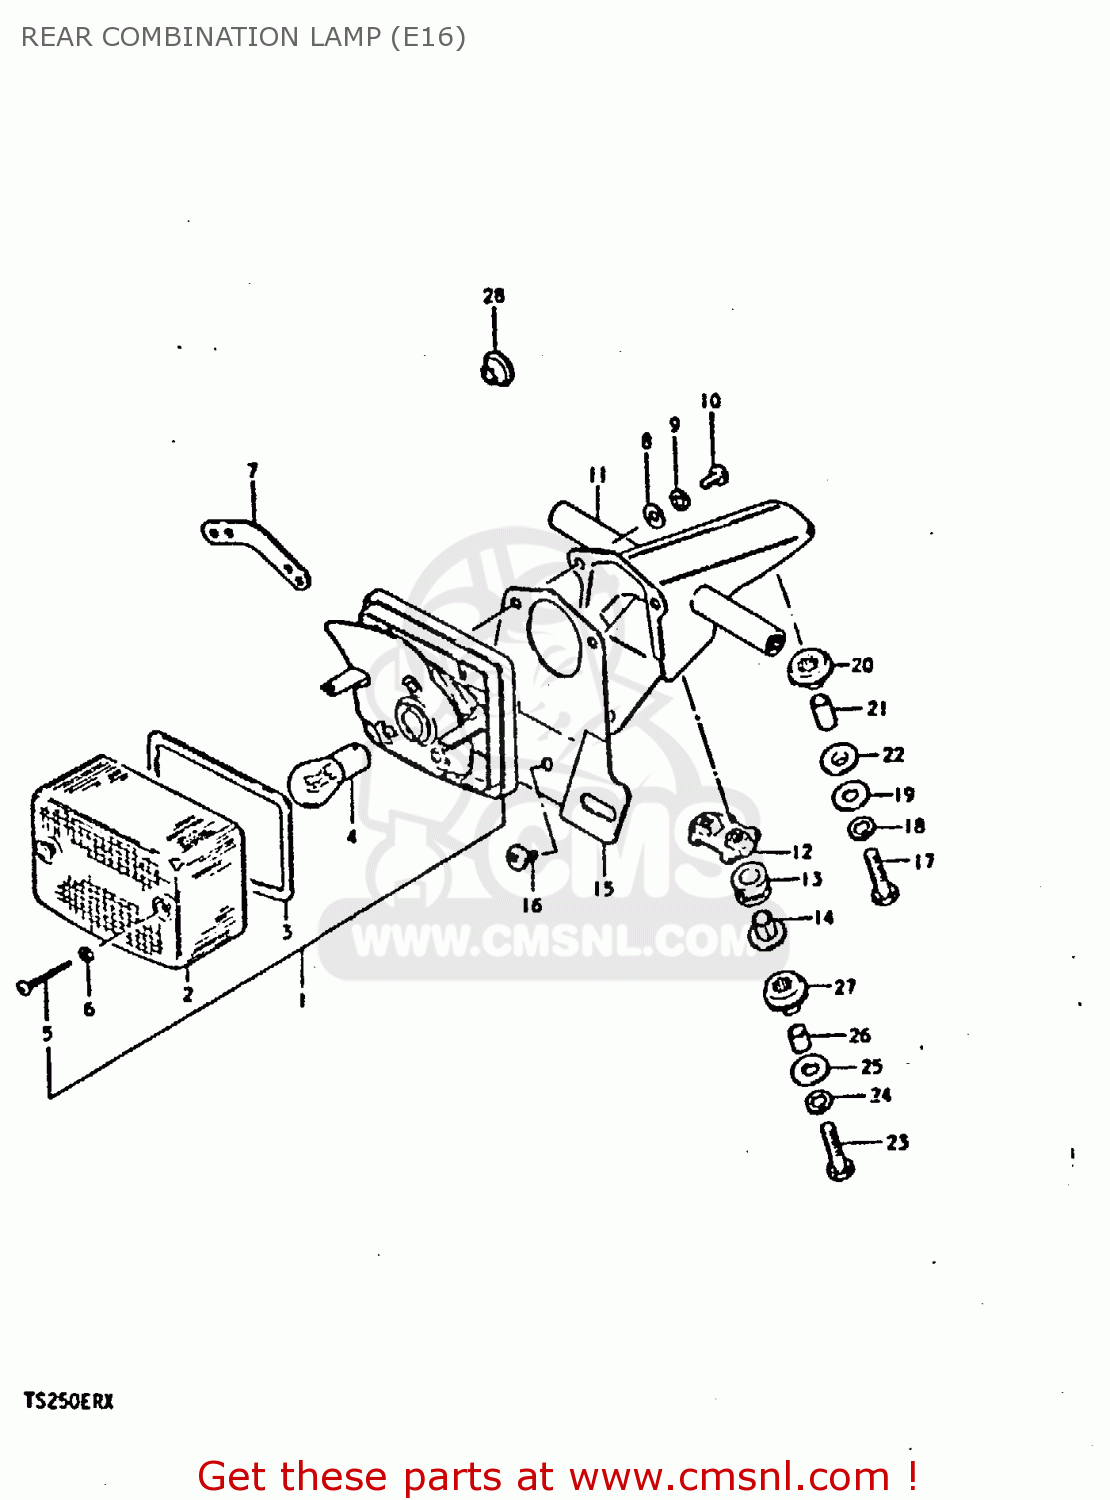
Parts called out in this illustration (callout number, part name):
1	LAMP UNIT, TAIL
2	LENS
3	GASKET (NAS)
4	BULB (6V,21/5W)
5	BOLT
6	GASKET (NAS)
7	PLATE,REAR COMBINATION LAMP
8	WASHER
9	LOCK WASHER
10	SCREW
11	BRACKET ASSY
12	PLATE
13	CUSHION
14	SPACER
15	PLATE, LICENSE
16	SCREW
17	BOLT
18	LOCK WASHER
19	WASHER (6.5X20X1.2)
20	CUSHION
21	SPACER
22	CUSHION
23	BOLT
24	LOCK WASHER
25	WASHER (6.5X20X1.2)
26	SPACER
27	CUSHION
28	GROMMET
